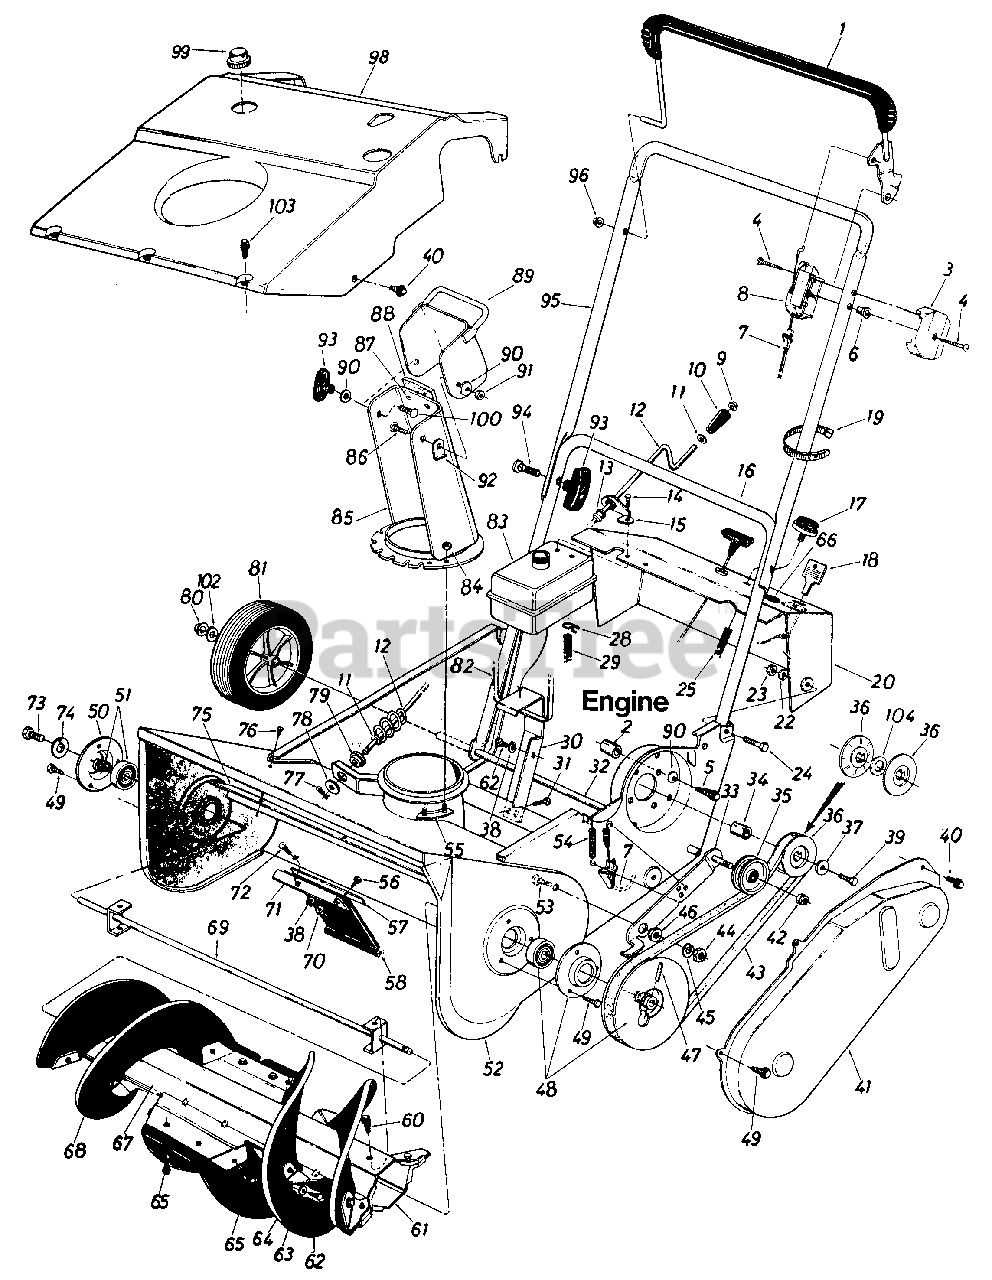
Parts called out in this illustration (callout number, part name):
2	SPACER
3	PANEL HALF-CONTROL
4	SCREW-TRUSS MACH
5	SCREW-HEX 5/16-18 X 1.50
6	PIN-CONTROL DISC
7	CABLE-CLUTCH
8	PANEL HALF-CONTROL
10	KNOB W/38 HOLE-BLACK
11	WASHER-FL-.385 ID X .62 OD X .063
12	CRANK ASSY-CHUTE
13	GROMMET
14	SCREW-HEX TAP 1/4 HI LO X .75
15	BRACKET-CHUTE CRANK
16	HANDLE-LOWER
17	PRIMER
18	KEY-STARTER-TEC
19	CLAMP-CABLE 7/8
20	PANEL-DASH
22	WASHER-LOCK-5/16
23	NUT-HEX 5/16-18
24	SCREW-HEX 5/16-18 X 1.50
25	HOSE-PRIMER
28	CLAMP-HOSE
29	FUEL LINE-15IN
32	AXLE-WHEEL
33	BRACKET ASSY-IDLER
34	SPACER-.635 ID X .890 OD X .80
35	PULLEY-IDLER
36	PULLEY-HALF-V
37	WASHER-BELL .337 X .867 X .057
38	LOCK WASHER 1/4 DIA
39	SCREW-HEX 5/16-24 X .75
40	SCREW-HEX L-WASH HD
42	NUT-HEX LOCK 3/8-24
43	BELT-V 1/2 X 34
44	NUT-HEX 5/16-18
45	WASHER-LOCK-5/16
46	SPACER-SHLD
47	PIN-SPRING SPIR
48	KIT-BRG CUP & PULLEY
49	SCREW-HEX B-TAP 1/4 X .38
52	HOUSING ASSY-BLOWER
53	SCREW-TRUSS MACH 5/16-18 X .75
54	SPRING-EXTENSION
55	GUARD ASSY-CHUTE FLANGE
56	SCREW-HEX WASH HD
57	STRIP-RETAINING
60	SCREW-HEX L-WASH HD
61	AUGER HALF-21 IN
62	SCREW-HEX WASH SF TAPP
63	WASHER-FL-.28 ID X .74 OD X .063
64	SPIRAL-RUBBER
65	SCREW-HEX B-TAP 1/4-.62
67	AUGER HALF-21 IN
68	SPIRAL-RUBBER
69	AXLE ASSY-AUGER
70	NUT-HEX 1/4-20
71	KIT-SHAVE PLATE
72	BOLT-CARRIAGE 1/4-20 X .50
73	SCREW-HEX WASH 1/4-20X.75
74	LOCK WASHER 1/4 DIA
75	ANGLE-THROWER HSG
76	SCREW-HEX B-TAP 1/4 X .38
77	PIN-COTTER-3/32 DIA X .75
78	WASHER-FL-.390 ID X 1.50 OD X .075
79	BUSHING-HEX
81	WHEEL ASSY W/TIRE-6 X 1.5
82	TIE-CABLE
83	TANK-GAS
84	NUT-HEX CENTER L-1/4-20
85	CHUTE ASSY
86	BOLT-CARRIAGE 5/16-18 X .62
88	SEAL-CHUTE
89	CHUTE ASSY-TOP
90	WASHER-BELL .337 X .867 X .057
91	NUT-HEX CENTER L-5/16-18
92	STOP-TOP CHUTE
93	KNOB-HANDLE ASSY
94	BOLT-CARRIAGE 5/16-18 X 1.75
95	HANDLE-UPPER
96	NUT-SPEED
99	CAP-GAS
100	BOLT-CARRIAGE 5/16-18 X 1.00
102	WASHER-FL-.510 ID X .75 OD X .033
103	SCREW-TRUSS MACH
104	WASHER-FL-.635 ID X .93 OD X .060
